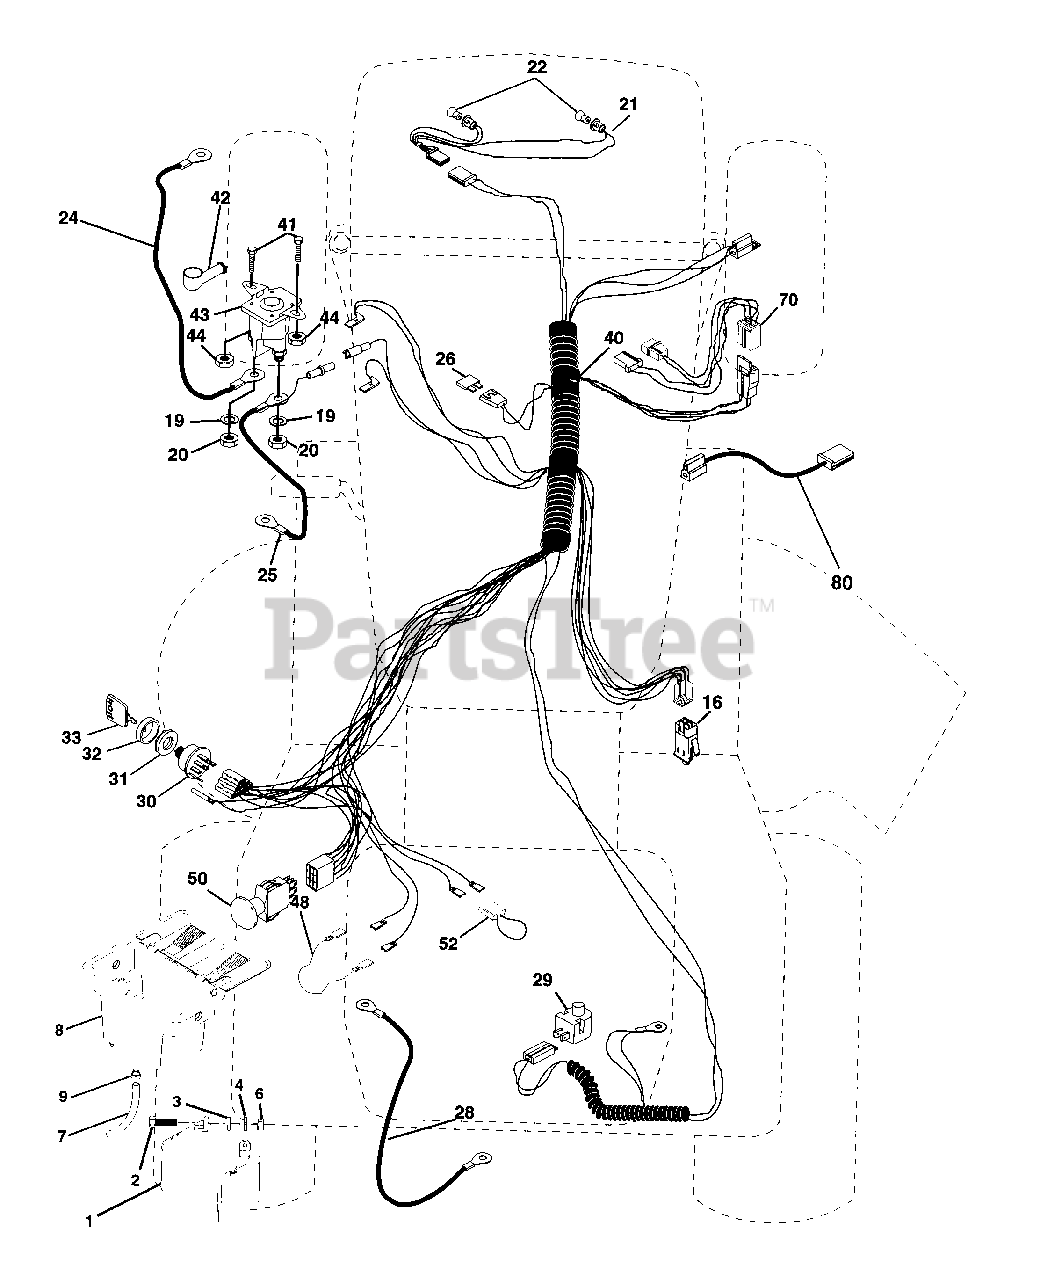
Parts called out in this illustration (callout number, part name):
1	Battery 12 Volt 25 AMP
2	Bolt Hex Hd 1/4-20 UNC X 3/4
3	Washer 9/32 X 5/8 X 16 Ga.
4	Washer Lock Hvy Helical 1/4
6	Nut Fin Hex 1/4-20 UNC
7	Tube Plastic 12"
8	Case Battery Mech Hinge
9	Clamp Hose Olive
16	Switch Interlock Push-In
19	Washer Lock 1/4
20	Nut Jam Hex 1/4-20 UNC
21	Harness Asm Light W/4152j
22	Bulb Light #1156
24	Cable Battery 6 Ga 11" red
25	Cable Battery 6 Ga 44" red w/16 wire
26	Fuse 30 AMP Auto Green
28	Cable Ground 6 Ga 12" black
29	Switch Plunger Nc Gray
30	Switch Ign 4 pos w/lights
31	Nut Ignition
32	Cover Sw Ignition
33	Key Ign Modelled Generic
40	Harness Ign.
41	Bolt Blk Fin Hex 1/4 - 20 x 1/2
42	Cover Terminal Red
43	Solenoid
44	Nut Keps Hex 1/4-20 UNC
48	Adapter Ammeter Rectangular
50	Switch, PTO 3PDT Black Delta 96
52	Protection Wire Loop
70	Harness, Eng. B & S 14 OHV Dual
80	Harness, Clutch EVX
